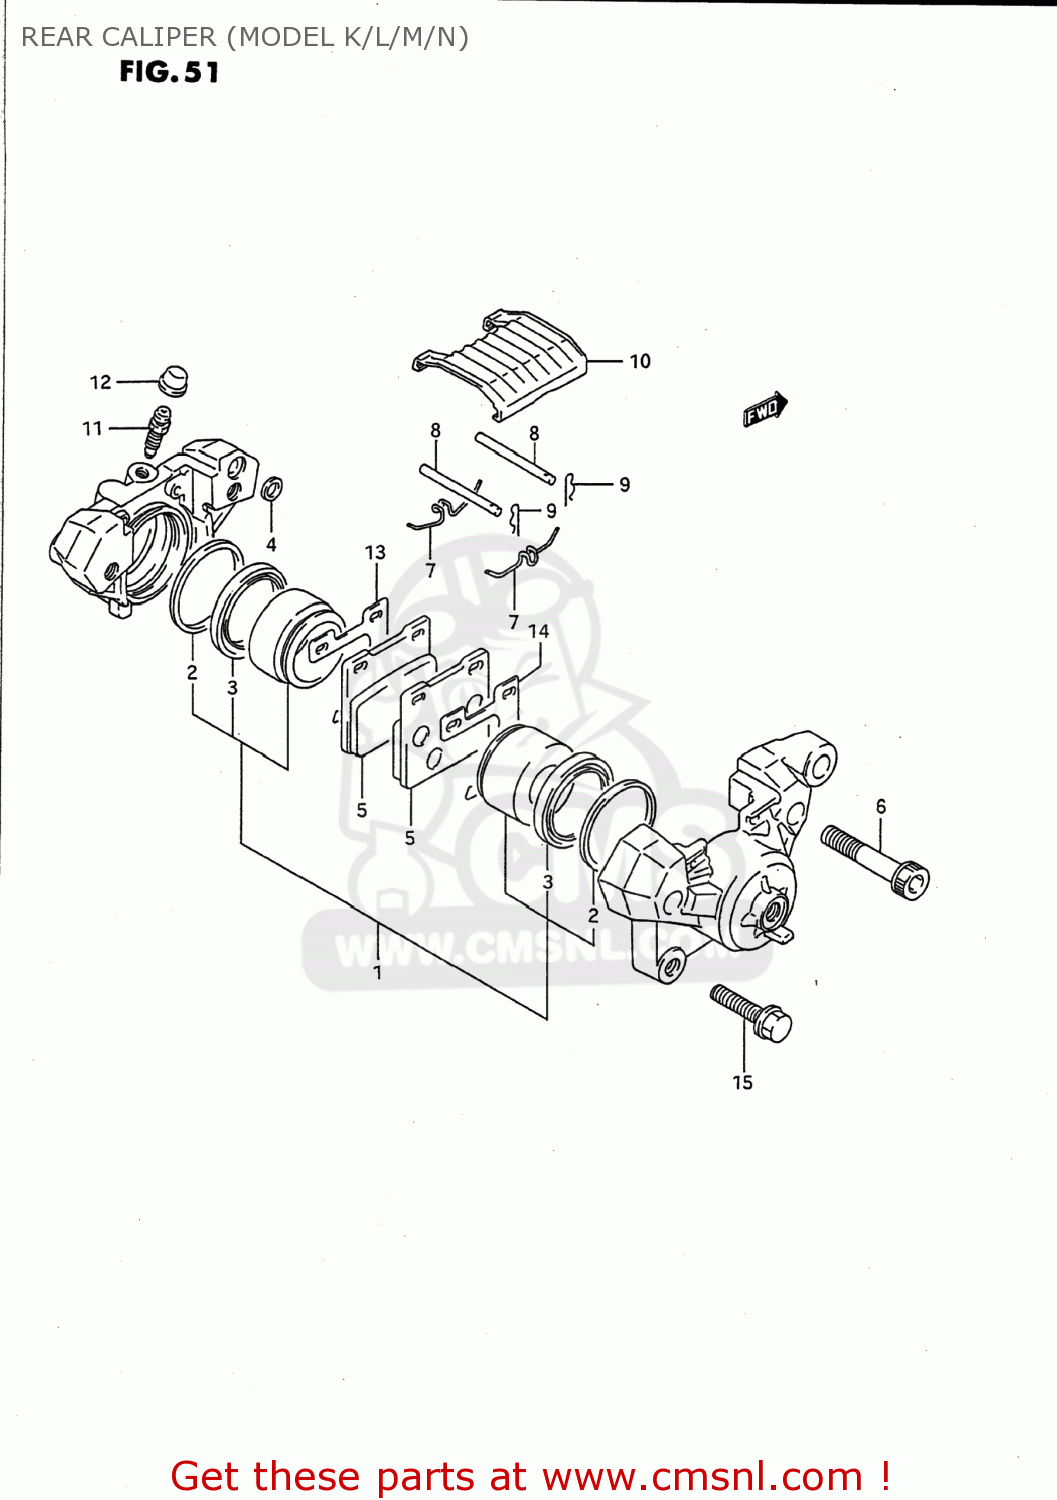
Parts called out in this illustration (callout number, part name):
1	PISTON SET
2	SEAL,PISTON
3	BOOT
4	SEAL,JOINT
5	PAD,BRAKE
6	BOLT
7	SPRING
8	PIN,PAD
9	CLIP,PAD PIN
10	COVER
11	BLEEDER
12	CAP,BREATHER
13	SHIM,INNER
14	SHIM,OUTER
15	BOLT
